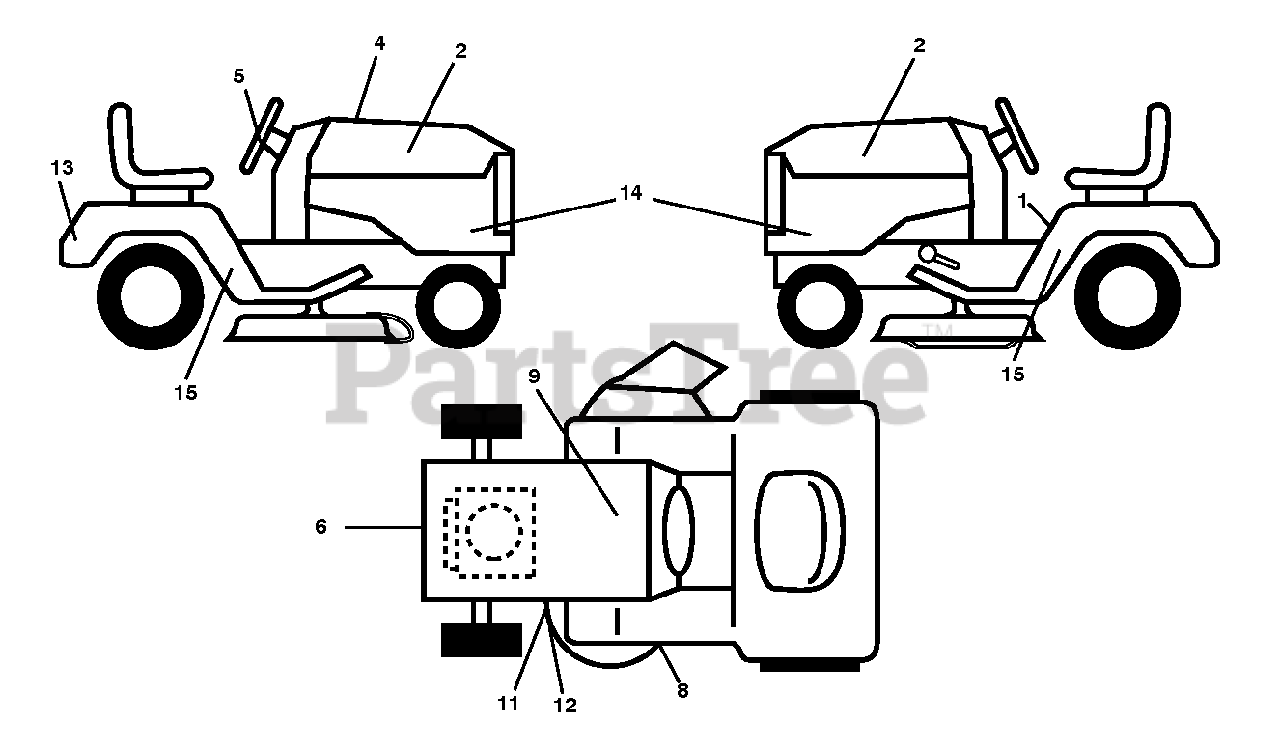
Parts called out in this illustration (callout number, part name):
1	Fender Warning Decal, English
2	DECAL.HOOD.POULAN.PRO.SET
5	DECAL.STEER.WHEEL.POULAN.PRO
6	DECAL.ENG.BS.26 HP.PROF.278955
8	DECAL.MOWER.SCH.48/54
9	DECAL BTRY SYMBOLS
11	DECAL.MOWER
12	DECAL.WARN.KEEP.HAND.AWAY
13	DECAL.REAR.FNDR.LOGO.POULAN.PR
